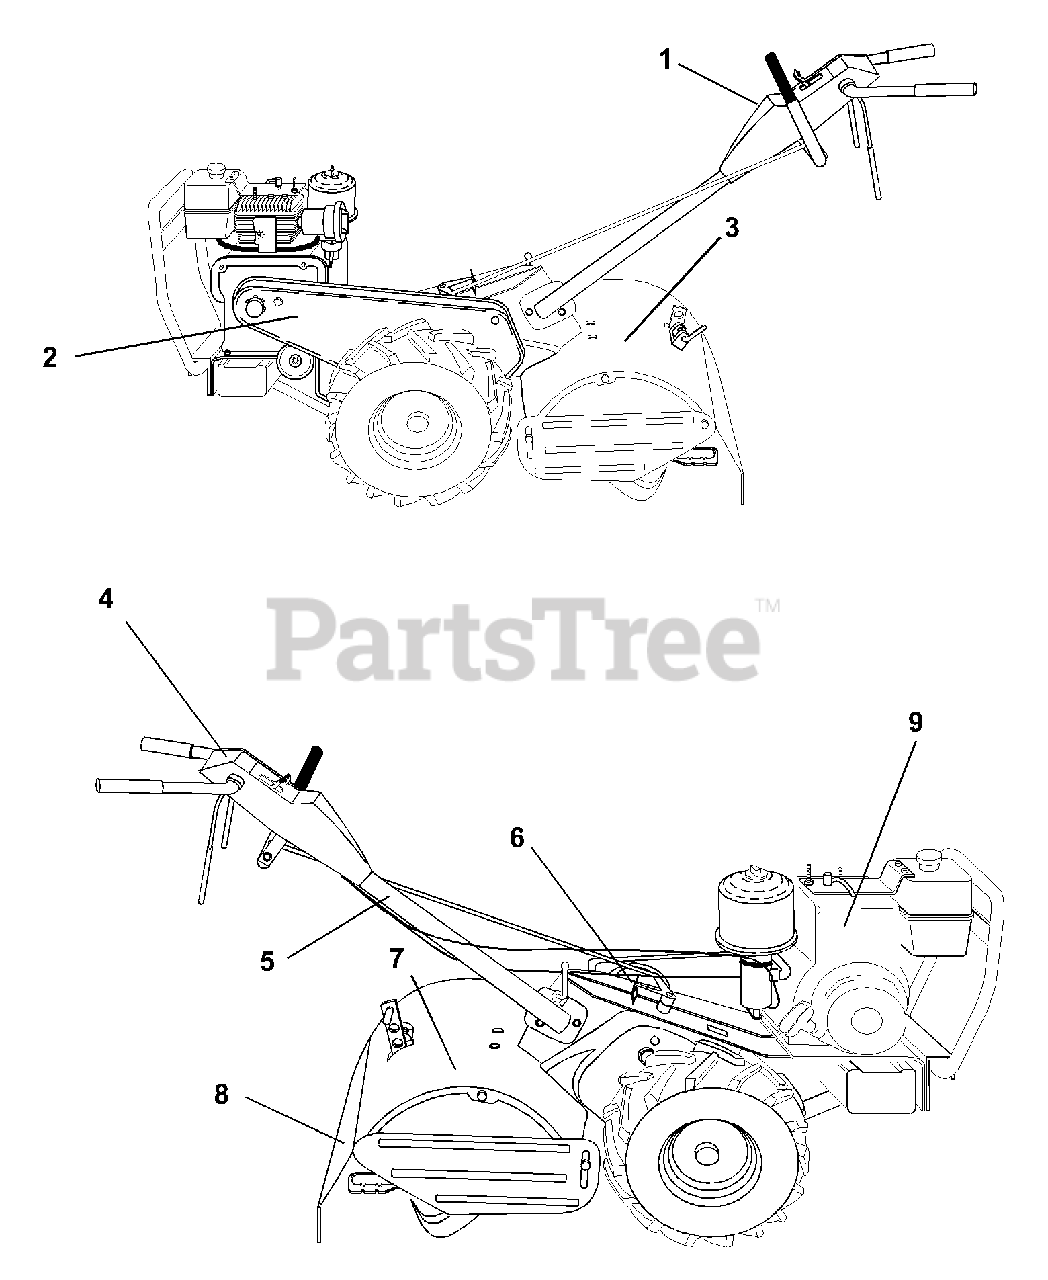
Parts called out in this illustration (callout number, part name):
1	Decal, Logo
2	Decal, Logo
3	Decal, Logo
4	Decal, Instruction, Tilling
5	Decal, Hand Placement
6	Decal, Shift Indicator
7	Decal, Caution
8	Decal, Warning, Rotating Tines
9	Decal, Briggs & Statton
